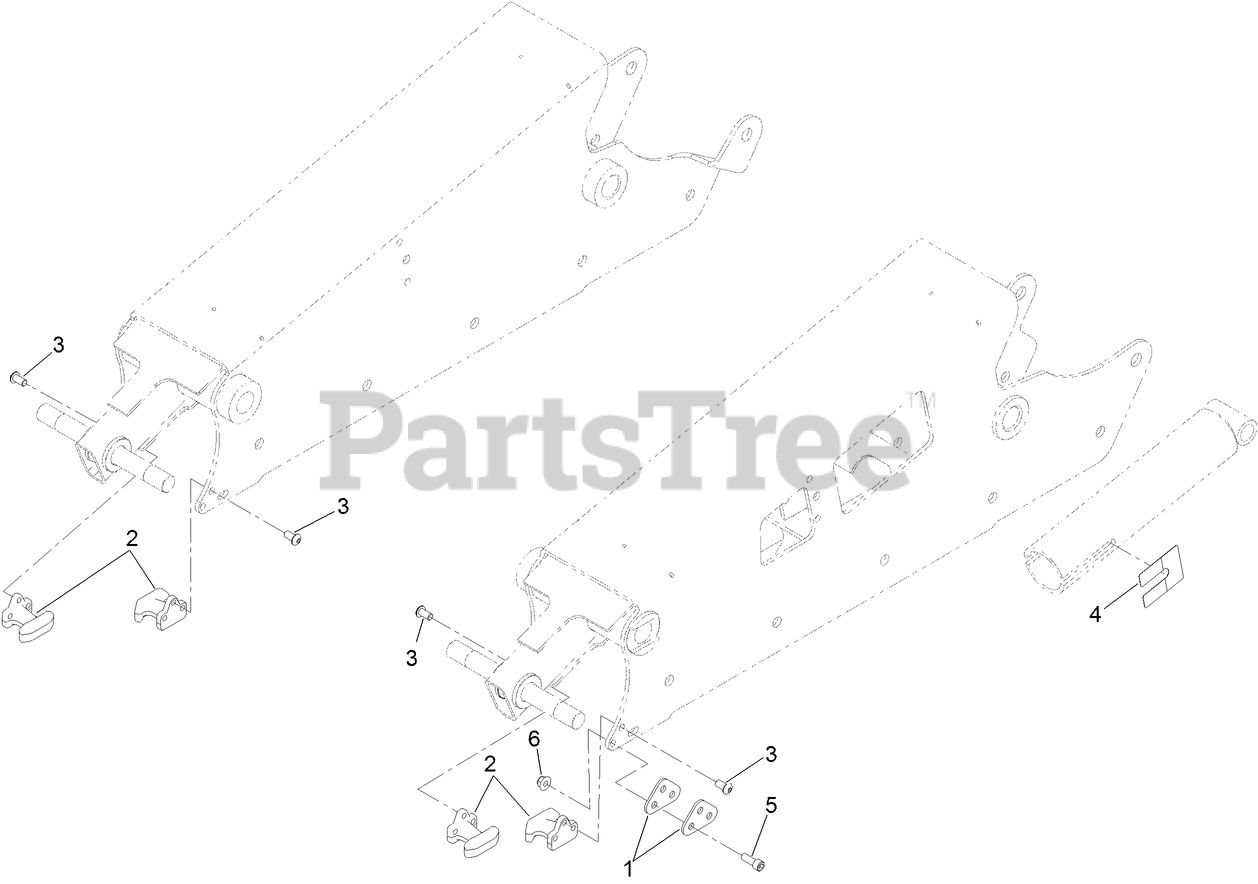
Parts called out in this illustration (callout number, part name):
1	PLATE-TEMPLATE
2	TRACK-GUIDE
3	SCREW-HH
4	DECAL-INDICATOR, TENSIONER
5	SCREW-HSH
6	NUT-HF, NI
